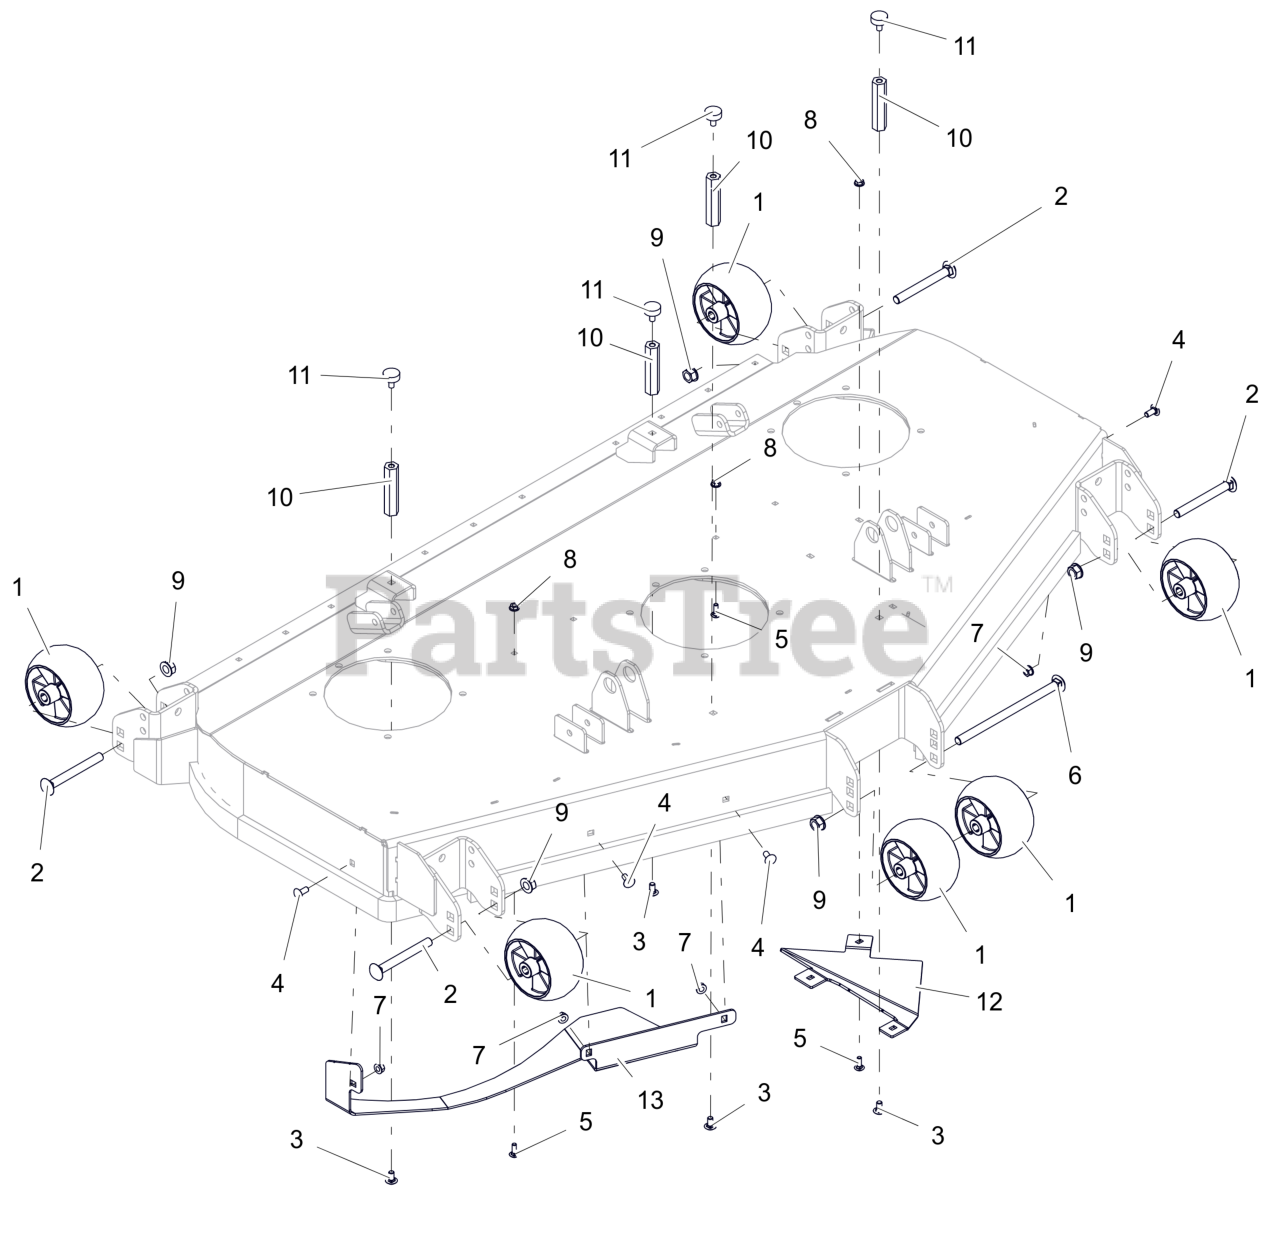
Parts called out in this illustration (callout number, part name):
1	WHEEL, ANTI SCALP - 5X3 CTR W/RIBS
2	BLT,RHSN .50-13X4.50 G5 ZCC
3	BTL,RHSSN .313-18 X 0.625 G5 ZCC
4	BLT, RHSSN.31-18X.750 G5 ZCC
5	BLT, RHSN .25-20X.750 G5 ZCC
6	BTL,RHSN .500-13 X 8.5S G5 ZCC
7	NUT,LK-CTR-FLG .31-18 GF ZCC
8	NUT-LK-CTR-FLG .25-20 ZC120
9	NUT-LK-CTR-FLG .500-13 GG ZCC
10	NUT, COUPLING .312-18 X 3.375
11	BUMPER, RUBBER
12	BAFFLE, INSERT TRIANGLULAR (RED)
13	DEFLECTOR, BAFFLE BOLT-IN (RED)
